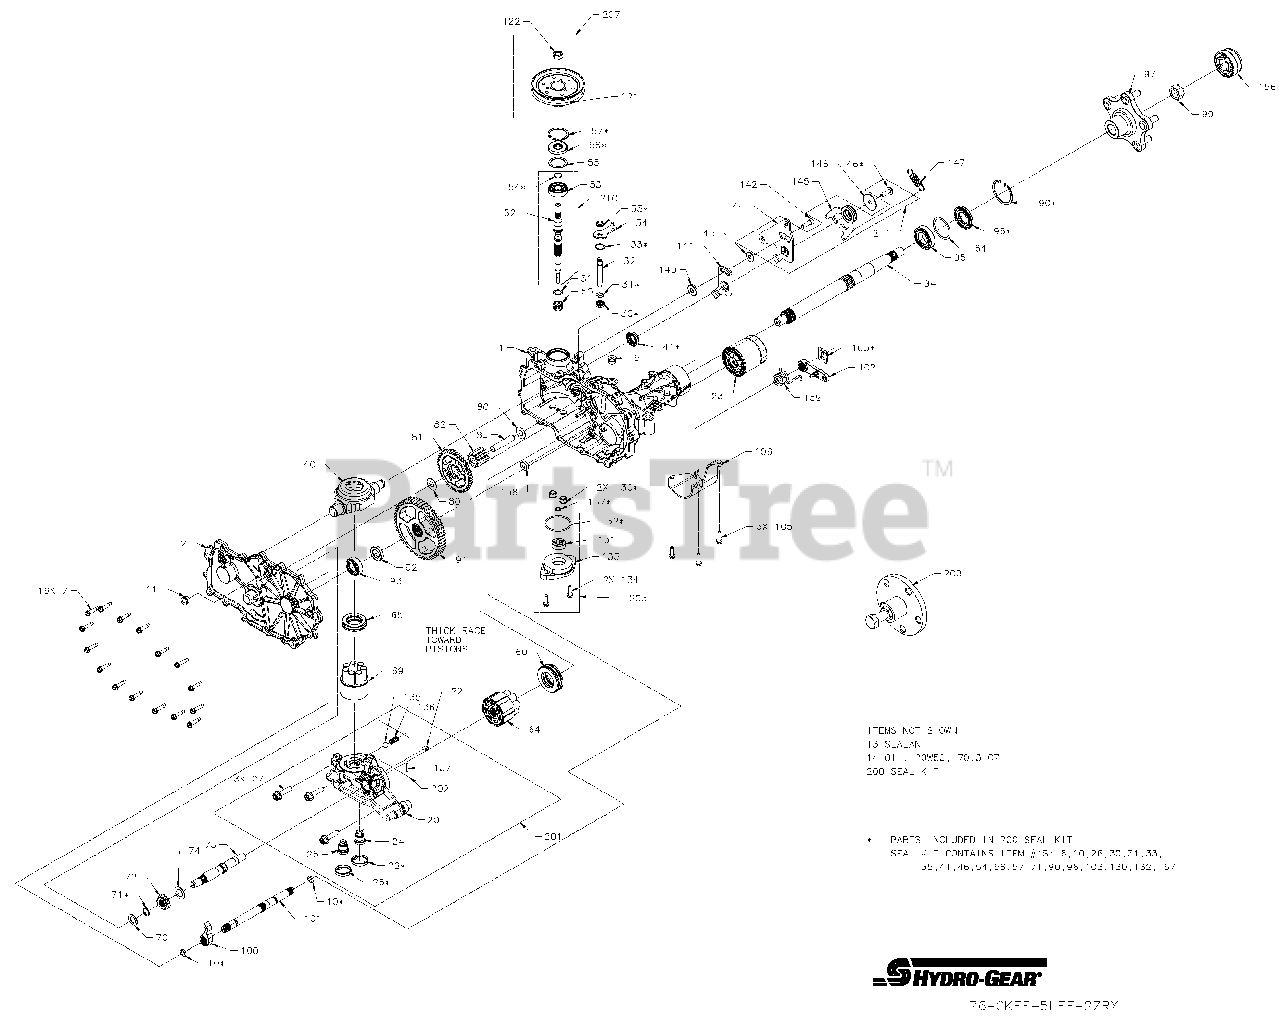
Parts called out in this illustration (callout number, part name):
13	SEALANT
23	FILTER, OIL
30	SEAL, LIP .375X.75X.25
31	RING, RET .375 EXTRNL
35	RING, RTNG .375 EXT
40	TRUNNION, SWASHPLATE
41	SEAL, LIP 12 X 32 X 7
46	TWHCS 5/16-24 X 1.00 (PATCH)
51	WASHER-FLAT .59 X .79 X .04
55	WASHER 1.23X1.56X.04
57	RING, RETAINING
69	ASS'Y, BLOCK 7 PISTON
80	WASHER .5X1.0X.03
99	NUT, HEX LOCK 3/4-16
122	NUT,HEX LOCK 1/2-20 NYLON INSERT
132	O-RING, -137, 0.103 X 2.050
146	WASHER, .343 X 1.500 X .062
147	SPRING, EXTENSION
